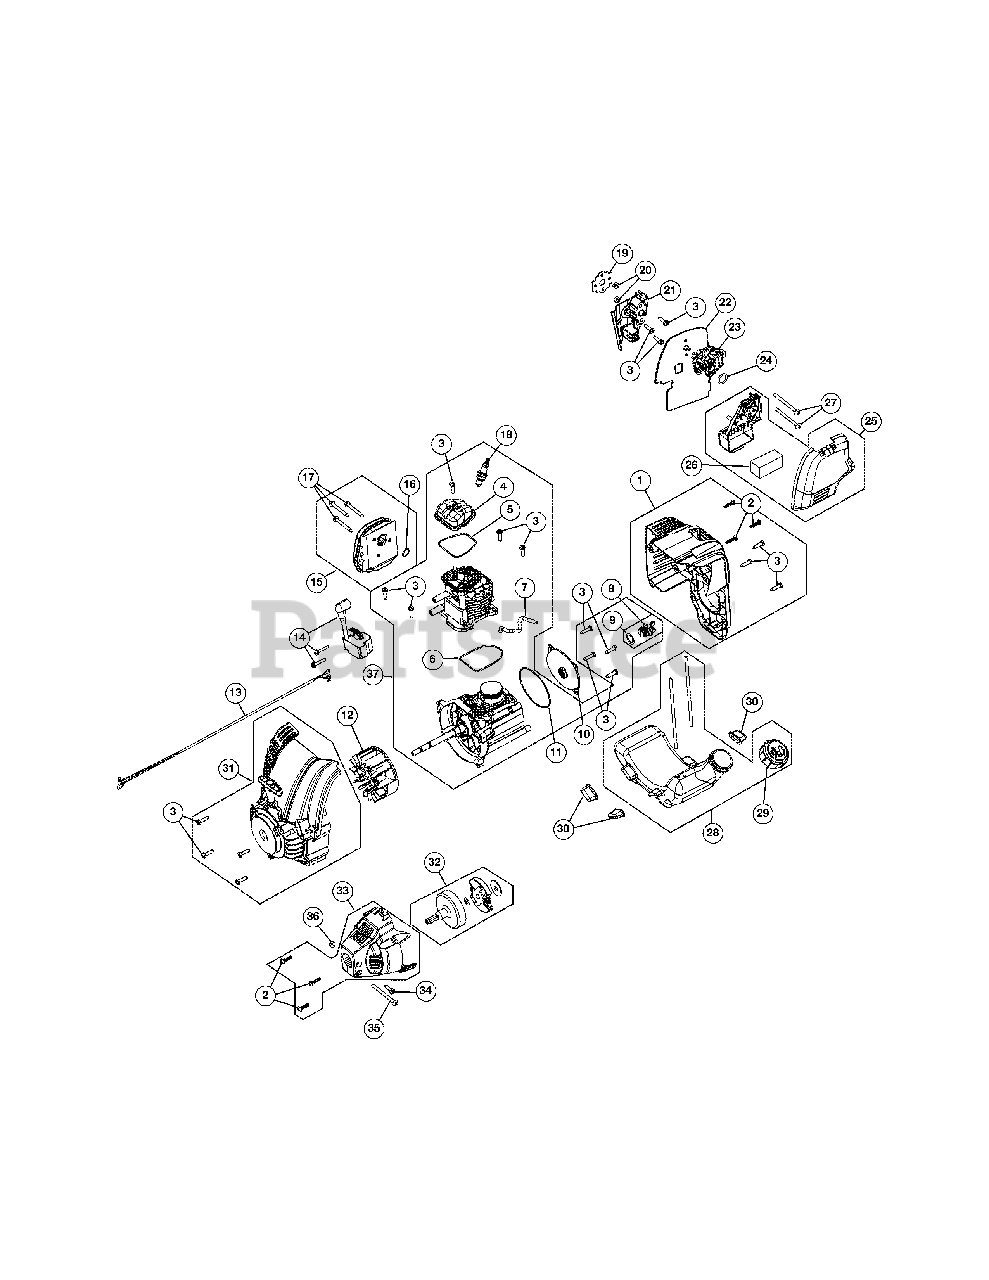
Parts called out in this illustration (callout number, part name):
1	Engine Cover Assembly (Incl Ref No. 2 & 3)
2	Cover Screw
3	Screw
4	Rocker Cover
5	Rocker Cover O-Ring
6	Cylinder O-Ring
7	Breather Hose
8	Oil Plug (Incl Ref No. 9)
9	Oil Plug O-Ring
10	Crankcase Cover
11	Crankcase Cover O-ring
12	Flywheel Assembly
13	Lead Wires
14	Module Assembly
15	Muffler Assembly (Incl Ref No. 16 & 17)
16	Muffler Gasket
17	Muffler Screw
18	Spark Plug
19	Insulator Gasket
21	Insulator
22	Carburetor Gasket
23	Carburetor w/Primer
24	Air Cleaner O-Ring
25	Air Cleaner Cover Assembly (Incl Ref No. 32)
26	Air Filter
28	Fuel Tank Assembly w/Fuel Lines (Incl Ref No. 35)
29	Fuel Cap
30	Fuel Tank Pads
31	Starter Housing Assembly (Incl Ref No. 3 & 37-45)
32	Clutch Assembly
33	Clutch Cover (Incl Ref No. 2)
34	Anti-Rotation Screw
35	Clamp Screw
37	Shortblock Assembly
